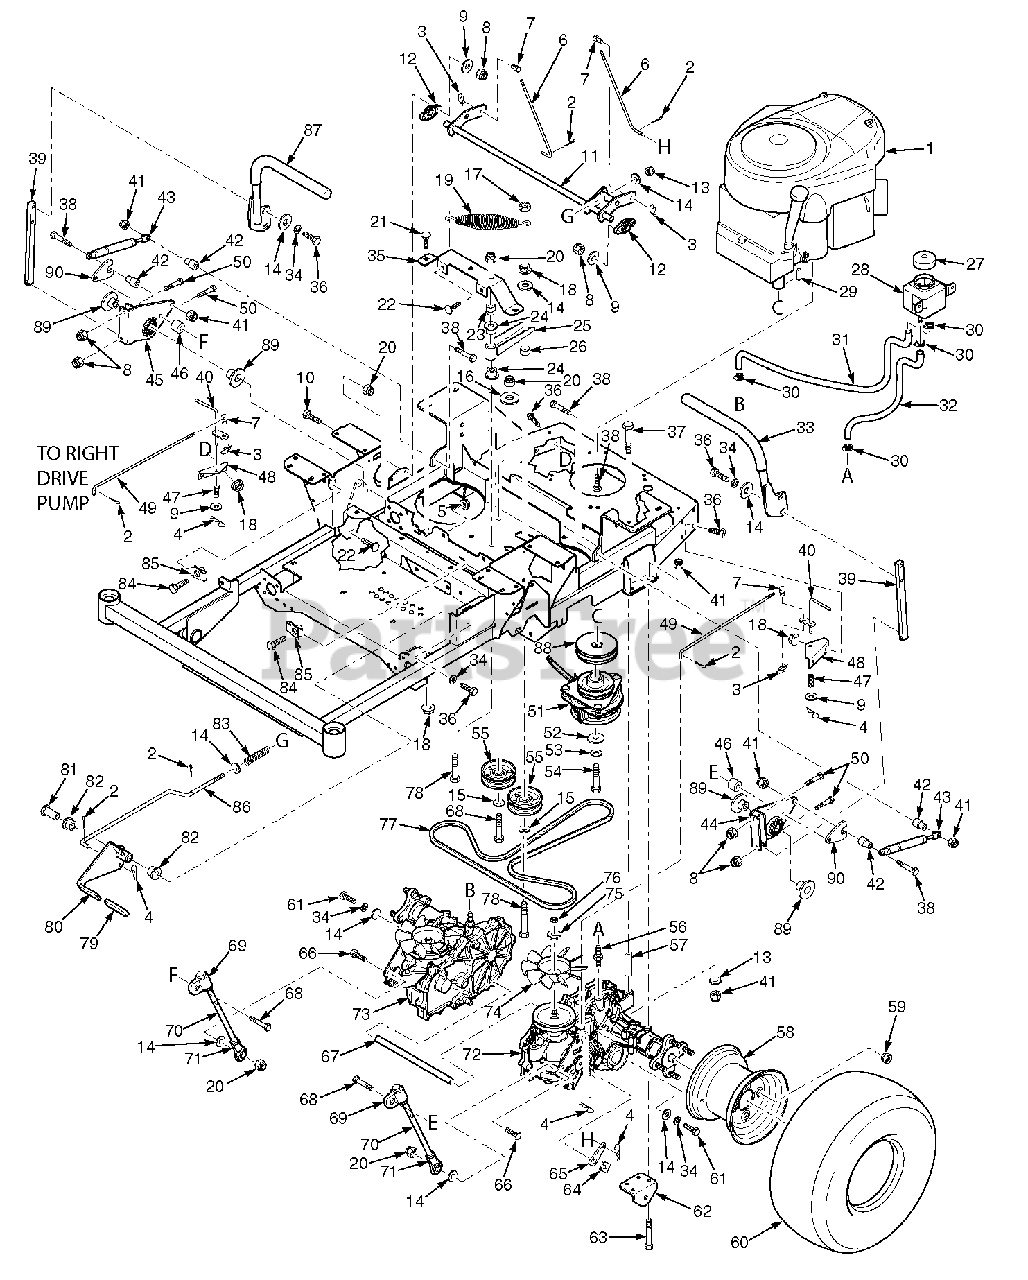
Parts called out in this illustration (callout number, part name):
1	Engine, Briggs & Stratton Pro-Series
1	Engine, Kawasaki FS600V
2	Cotter Pin, 3/32 x 1"
3	Pin, Rue Cotter 3/8" Dia.
4	Hair Pin, .080 x 1.19"
5	Nut, Serrated Flange 5/16-18
6	Rod, Brake Adjustment
7	Joint, Swivel
8	Nut, Elastic Stop 1/4-20
9	Flatwasher, 1/4-.312 x .750 x .065
10	Bolt, Serrated Flange 1/4-20 x 1-1/4"
11	Weldment, Brake Lever
12	Bearing
13	Flatwasher, 5/16-.375 x .875 x .083
14	Flatwasher, 3/8-.391 x .938 x .105
15	Flatwasher, 3/8-.391 x .938 x .105 HD
16	Flatwasher, 3/8-.406 x 1.5 x 7 GA.
17	Nut, Center Lock 3/8-16
18	Nut, Serrated Flange 3/8-16
19	Spring, Transmission Idler
20	Nut, Elastic Stop 3/8-16
21	Bolt, Carriage 3/8-16 x 3/4"
22	Bolt, Carriage 5/16-18 x 3/4"
23	Shaft Pivot, Idler Arm
24	Bearing
25	Transmission Idler Arm Assembly
26	Spacer, Idler Pulley
28	Reservoir Assembly
29	Key, 1/4 x 1/4 x 1-3/4"
30	Clamp, 0.87" Max Dia.
31	Hose, RH Transmission
32	Hose, LH Transmission
33	Handle Bar Assembly LH, w/Grip
34	Lockwasher, 3/8" Spring
35	Support, Idler Arm
36	Bolt, Hex Head 3/8-16 x 1"
37	Bolt, Hex Head 5/16-18 x 5"
38	Bolt, Hex Head 5/16-18 x 1-1/2"
39	Bar, Control Lever
40	Dump Valve Lever
41	Nut, Elastic Stop 5/16-18
42	Spacer, Pump Dampener
43	Dampener
44	Control Link, LH
45	Control Link, RH
46	Spacer
47	Spring
48	Bracket, Dump Mounting
49	Linkage, Dump Valve
50	Bolt, Hex Head 1/4-20 x 1-1/2"
51	Electric Clutch Assembly
52	Flatwasher, 7/16-.469 x 1.75 x .25
53	Lockwasher, 7/16" spring
54	Bolt, Hex Head 7/16-20 x 2-1/4" Patch
55	Pulley, 3-1/2" Dia.
56	Fitting, Transmission
57	Spacer, Axle
58	Rim w/Valve Stem
59	Wheel Nut, 1/2-20
60	Wheel Assembly
60	Tire, 20 x 10-8 2-Ply
61	Bolt, Hex Head 3/8-16 x 2-1/4"
62	Bracket, Pusharm Link
63	Bolt, Hex Head 5/16-18 x 3"
64	Clip, Brake Lever (order through Hydro-Gear)
65	Lever, Brake (order through Hydro-Gear)
66	Bolt, Hex Head 3/8-16 x 1-1/4"
67	Spacer, Axle
68	Bolt, Hex Head 3/8-16 x 2"
69	Rod End, Adjustable
69	Nut, Jam 3/8-24 UNF RH
70	Linkage, Pump
71	Stake, Rod End Assembly
72	Transaxle Assy., (ZL-KCEF-3LKG-1NXX)
73	Transaxle Assy., (ZL-GCEF-3LKF-1NXX)
74	Fan (order through Hydro-Gear)
75	Nut, Control Linkage
76	Fan Nut (order through Hydro-Gear)
77	Belt, Transmission Drive
78	Bolt, Hex Head 3/8-16 x 3"
79	Grip, Brake Handle
80	Brake Handle Assembly
81	Spacer, Brake Handle
82	Bearing
83	Spring, Brake
84	Bolt, Hex Head 3/8-16 x 1-1/4" Special Lock
85	U-Nut, 3/8-16
86	Rod, Brake Linkage
87	Handle Bar Assembly RH, w/Grip
88	Pulley, 4-1/2" Dia. 1" Bore
89	Spacer, Linkage
